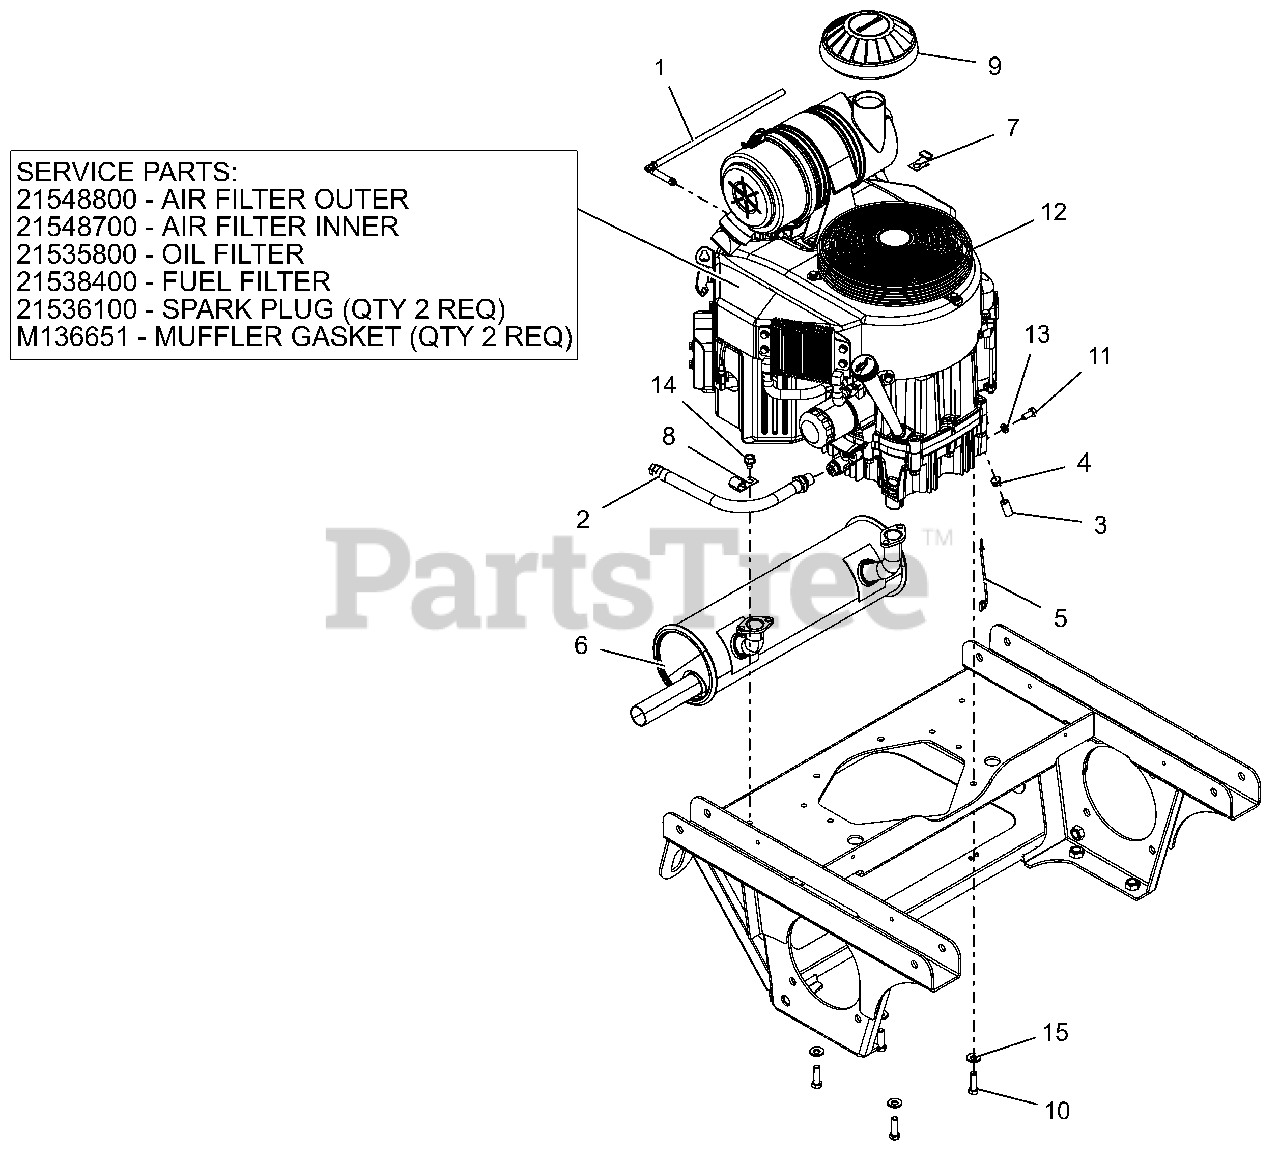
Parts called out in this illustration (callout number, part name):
1	ASM, VAPOR LINE
2	HOSE, OIL DRAIN
3	HOSE, .25 LOW-PERM BULK GAS
4	CLAMP, FUEL LINE
5	LEAD - STARTER SOLENOID
6	MUFFLER, 27-31 KAW
9	CAP, AIR CLEANER INTAKE (2")
10	BLT-HEX.38-16X1.25 G5YZ NYTORQ
11	@BLT-HEX M8-1.25X20 YWZC
12	ENGINE, KAWASAKI FX850
12	FILTER, OUTER
12	FILTER, INNER - KAW
12	FILTER,OIL - KAW
12	FUEL FILTER - KAWASAKI
12	PLUG, SPARK
12	GASKET, MUFFLER #
13	@WSHR-LK .31X.078 REG YWZC
14	@SCR-TAP .38-16X.50 HWH TR YWZ
15	WASHER, 3/8" SPRING DISC
